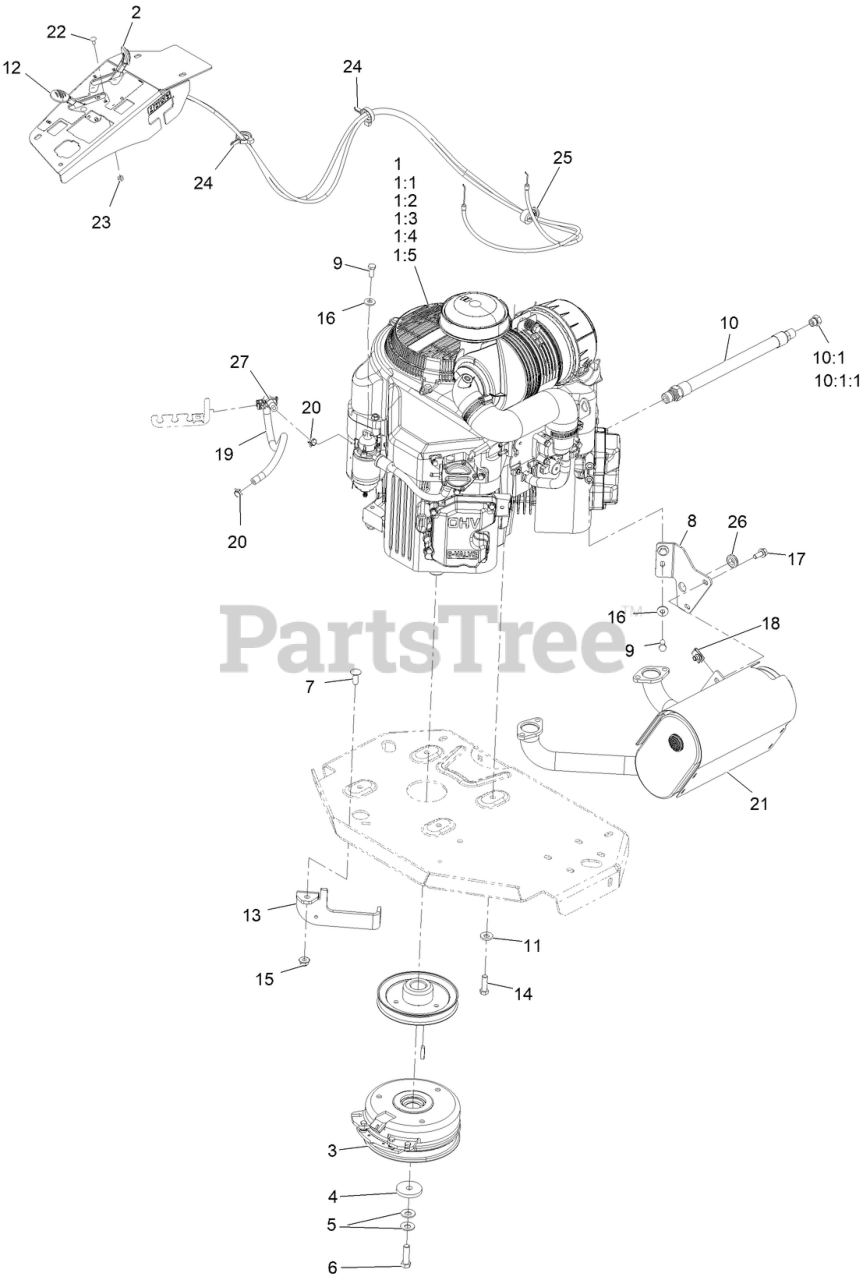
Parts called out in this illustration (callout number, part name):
1:1	FILTER-OIL KAW
1:2	ELEMENT-FILTER, AIR (OUTE
1:3	ELEMENT-FILTER, AIR (INNE
1:4	FILTER-FUEL
1:5	Spark Plug
2	CONTROL, CHOKE
3	CLUTCH KIT
4	WASHER-CLUTCH
5	WASHER-SPRING
6	SCREW-HH 7/16-20 X 1 1/2 W/LOCTITE
7	SCREW-CARR
8	BRACKET-MUFFLER MOUNT
9	SCREW-HH
10	ENGINE OIL DRAIN HOSE ASM
10:1	PLUG-HH
10:1:1	O-RING
11	WASHER-BELLEVILLE
12	ASM,THROTTLE CABLE
13	Bracket-Clutch Anchor
14	SCREW-HH
15	NUT-HF, NI
16	WASHER-SPRING
17	SCREW-HHF
19	HOSE-FUEL
20	CLAMP-HOSE
21	MUFFLER
22	BOLT-CARR
23	NUT-LOCK, NI
24	CLAMP-HOSE
25	Mount-Tie Wrap, Magnetic
26	GROMMET-RUBBER
27	Clip-Edge
